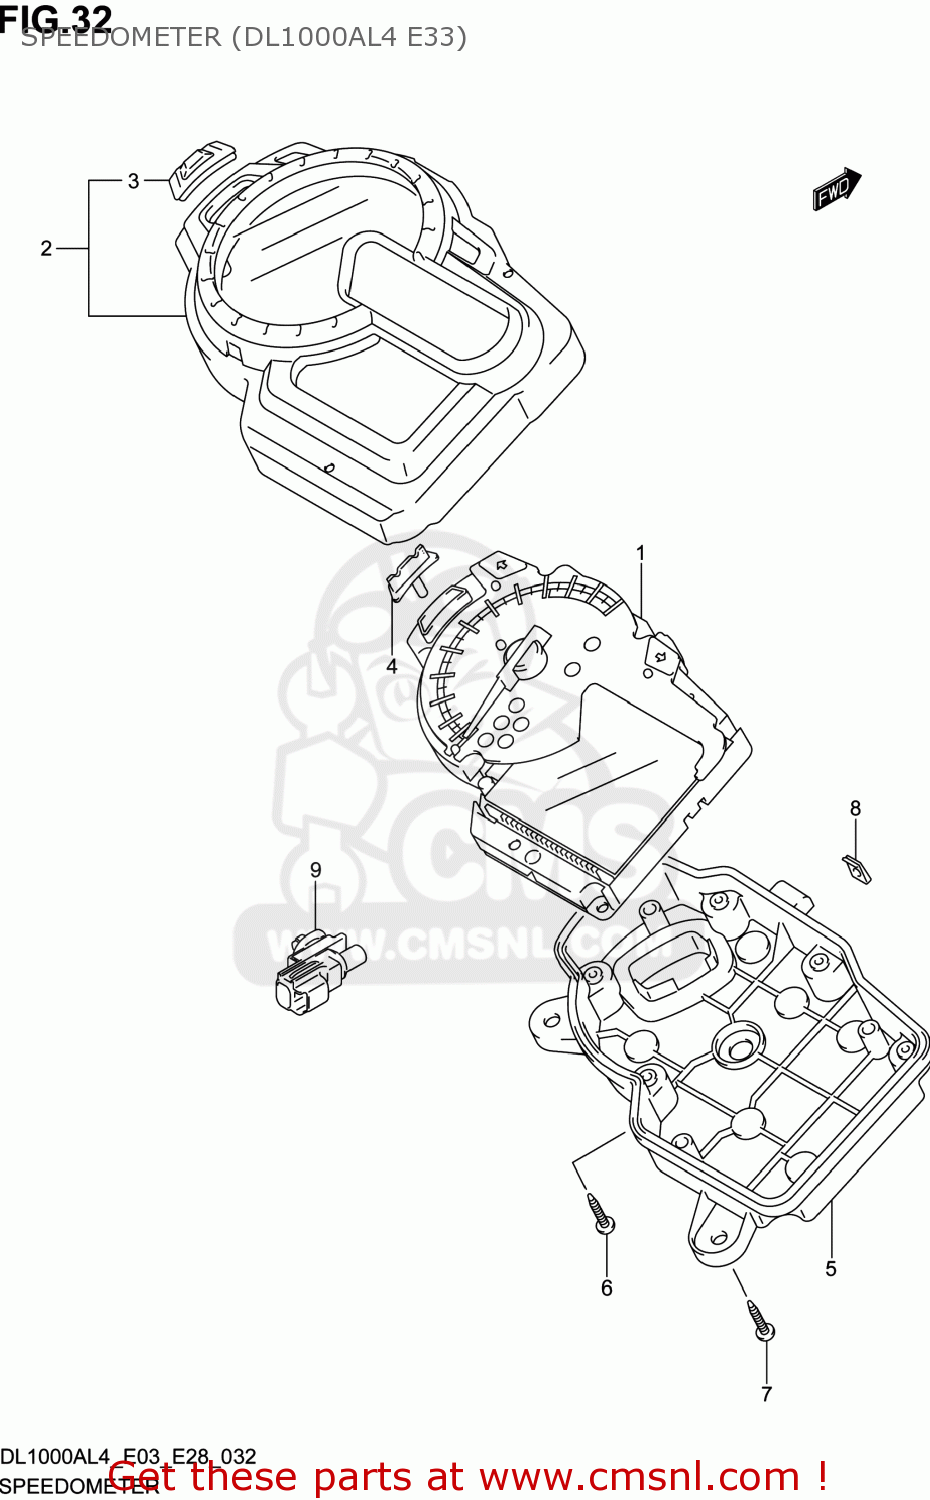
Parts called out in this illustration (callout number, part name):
1	SPEEDOMETER
2	CASE ASSY
3	RUBBER SWITCH
4	KNOB
5	CASE LOWER
6	SCREW(3X12)
7	SCREW
8	NUT
9	SENSOR,AIR TEMP
